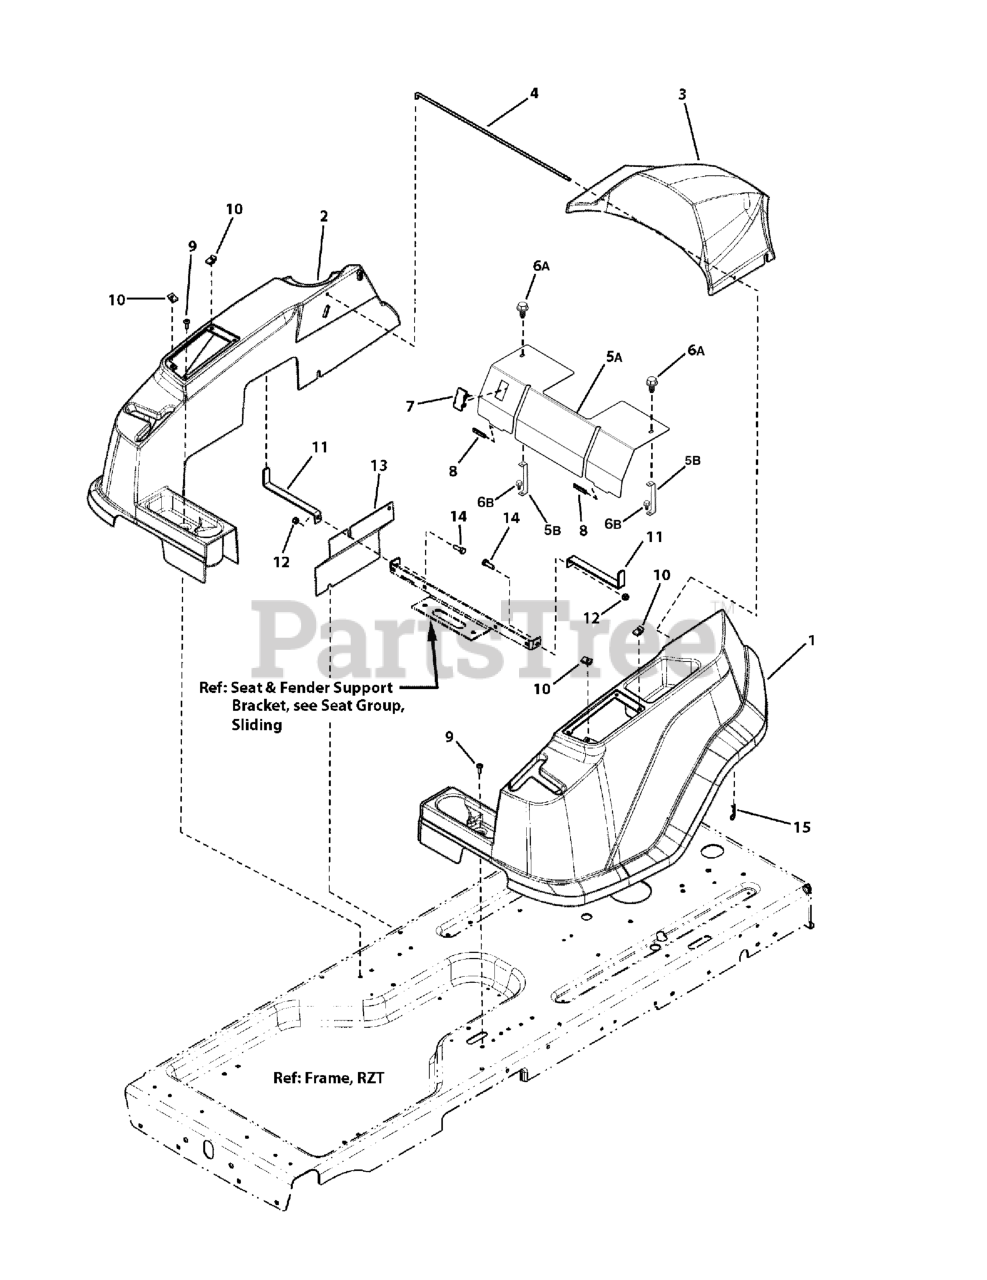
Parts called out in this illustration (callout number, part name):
1	FENDER, LH
2	FENDER, RH
3	COVER, Engine
4	ROD, Pivot, Hood
5A	COVER, BATTERY, 285z
5B	BRACKET, Battery Cover
6A	CAPSCREW, Hex Washer, Taptite, 1/4-20 x 1/2
6B	CAPSCREW, Hex Washer, Taptite, 3/8-16 x 3/4
7	PLUG, Hole
8	STRIP, TRIM
9	SCREW, 1/4-20 x 3/4, Pan Head Torx
10	U-NUT, 1/4-20
11	BRACKET, Support, Fender
12	NUT, 5/16-18 3B Nyloc, YZ
13	PLATE, Side, RH
14	SCREW, 5/16-18 x 1" Hex Head Cap, GR 5, YZ
15	HAIR PIN, 3/32 x 1-1/2", YZ
